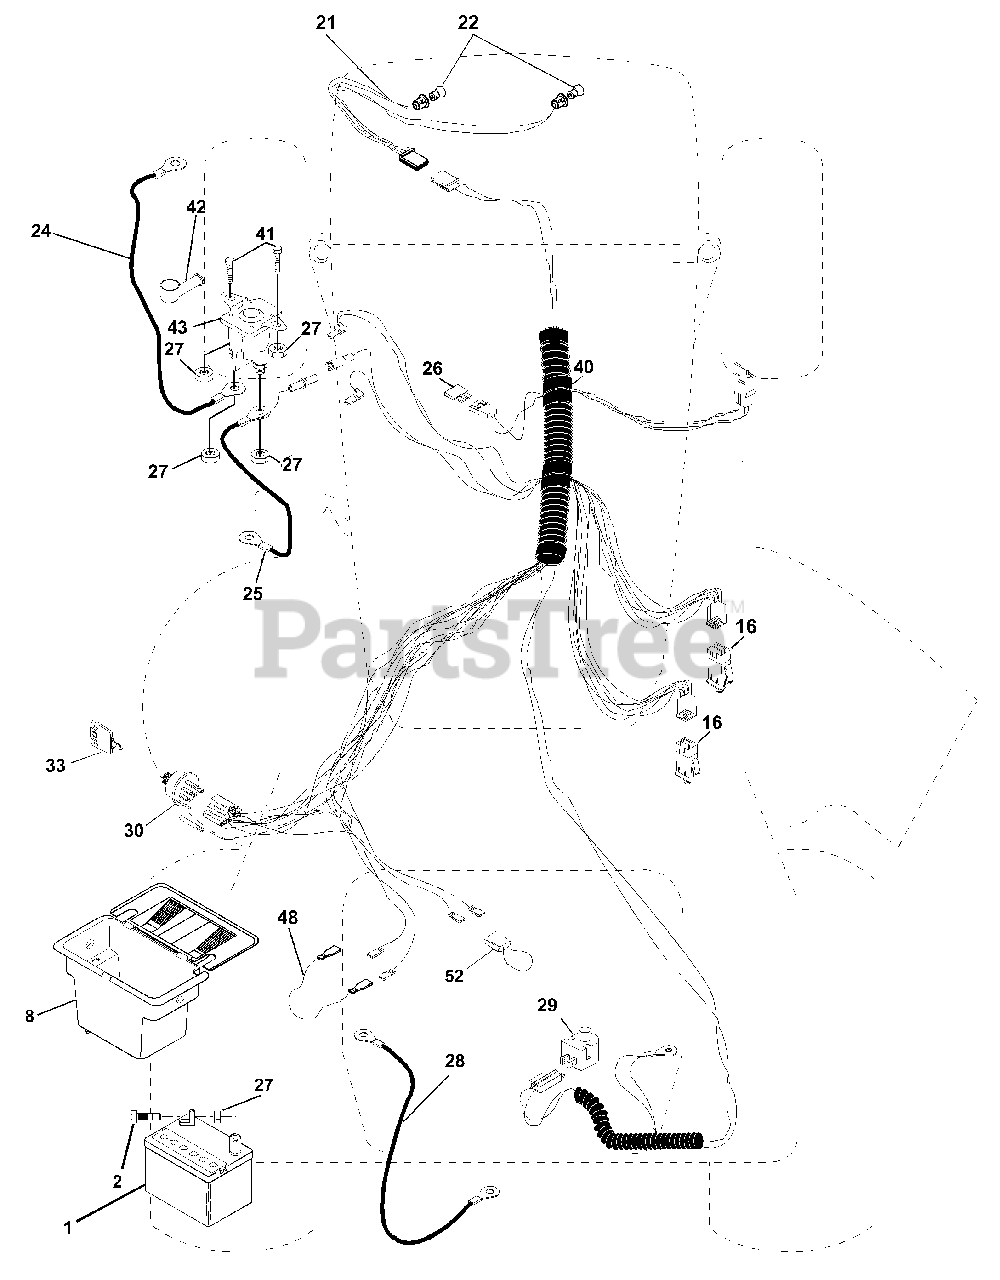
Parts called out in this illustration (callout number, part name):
1	Battery 12 Volt 25 Amp
2	Bolt Hex Hd 1/4-20unc X 3/4
8	Case Battery Mech Hiinge
16	Switch Interlock Push-In
21	Harness Asm Light W/4152j
22	Bulb Light #1156
24	Cable Battery 6 Ga 11" red
25	Cable Battery
26	Fuse 15 AMP
27	Nut Keps Hex 1/4-20 Unc
28	Cable Ground 6 Ga 12" black
29	Switch Plunger Nc Gray
30	Switch Ign
33	Key Ign
40	Harness Ign
41	Bolt Blk Fin Hex 1/4-20
42	Cover Terminal Red
43	Solenoid
48	Adapter Ammeter
52	Protection Wire Loop
